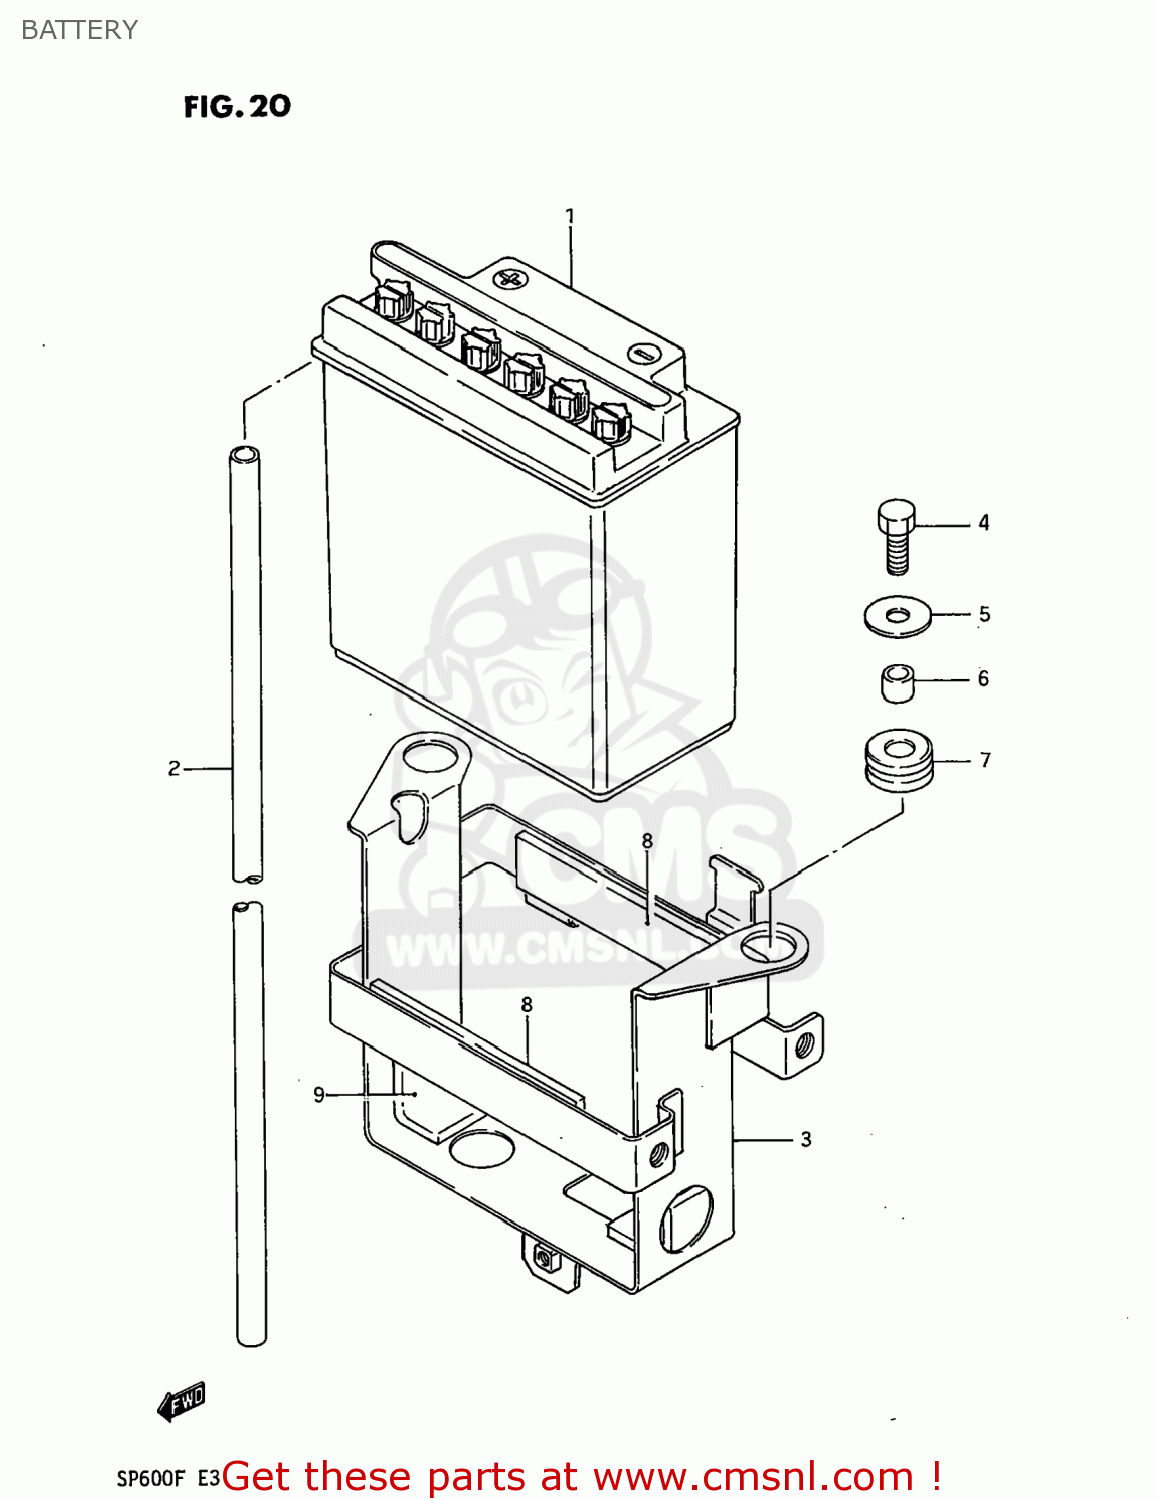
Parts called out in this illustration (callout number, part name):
1	BATTERY ASSEMBLY (12V)
2	HOSE,BATTERY EXHAUST
3	HOLDER,BATTERY
4	BOLT, UPPER
5	WASHER (6.5X20X1.2)
6	SPACER(6.1X9X7.5)
7	CUSHION
8	PROTECTOR,20X9
9	PROTECTOR(30X80X2)
